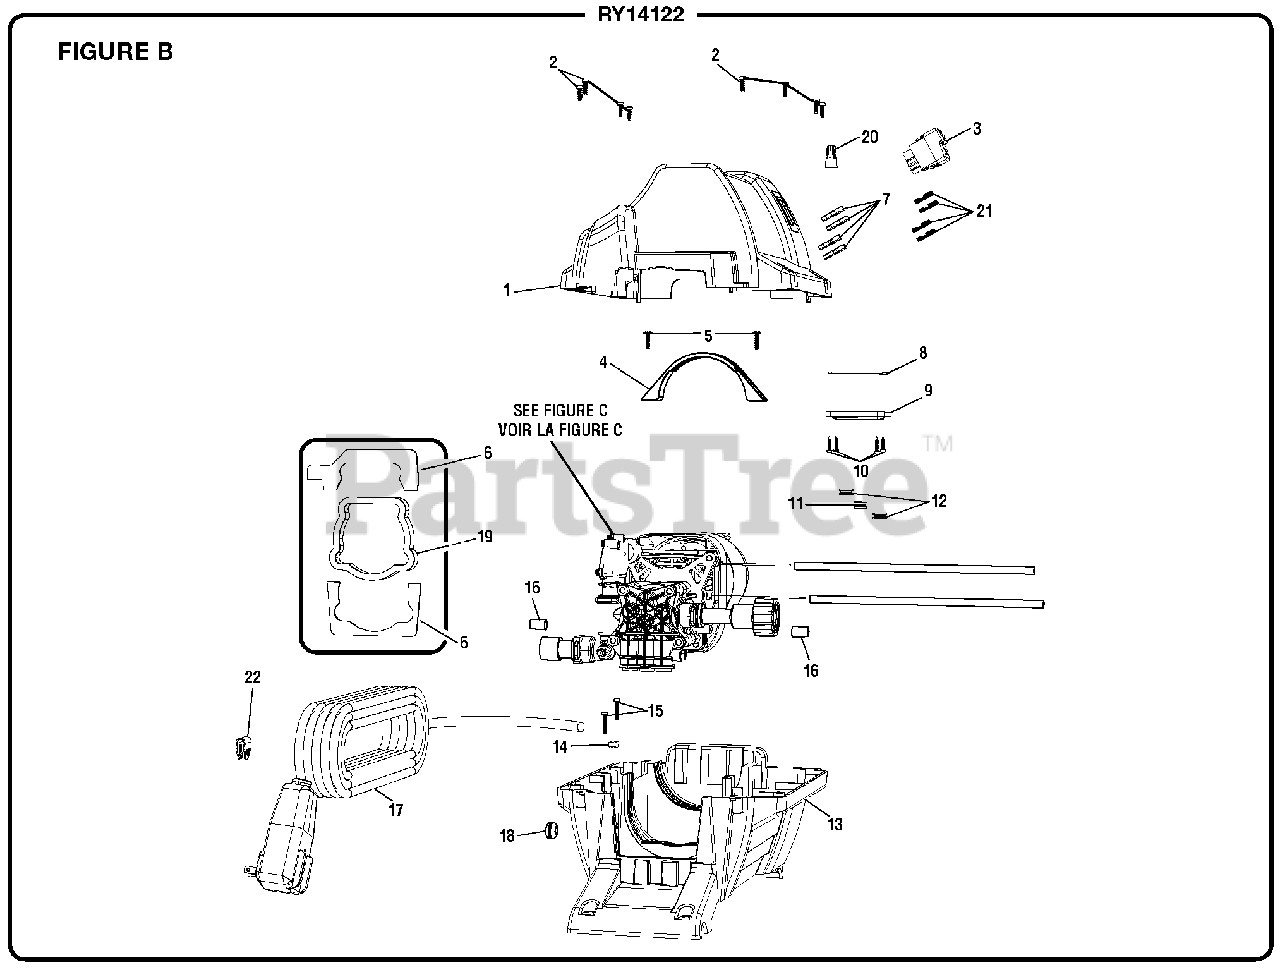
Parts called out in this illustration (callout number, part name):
1	Top Motor Housing
2	Screw (M4 x 15 mm)
4	Motor Bracket
5	Screw (M4 x 12 mm)
6	Upper and Lower Gasket Assembly
7	Sleeve Terminal
8	Switch Cover Gasket
9	Switch Cover
10	Screw (M3 x 14 mm)
13	Lower Motor Housing
14	Cord Clamp
15	Screw (M3.5 x 20 mm)
17	Power Cord
21	Brass Terminal
22	Electric Cord Clip
